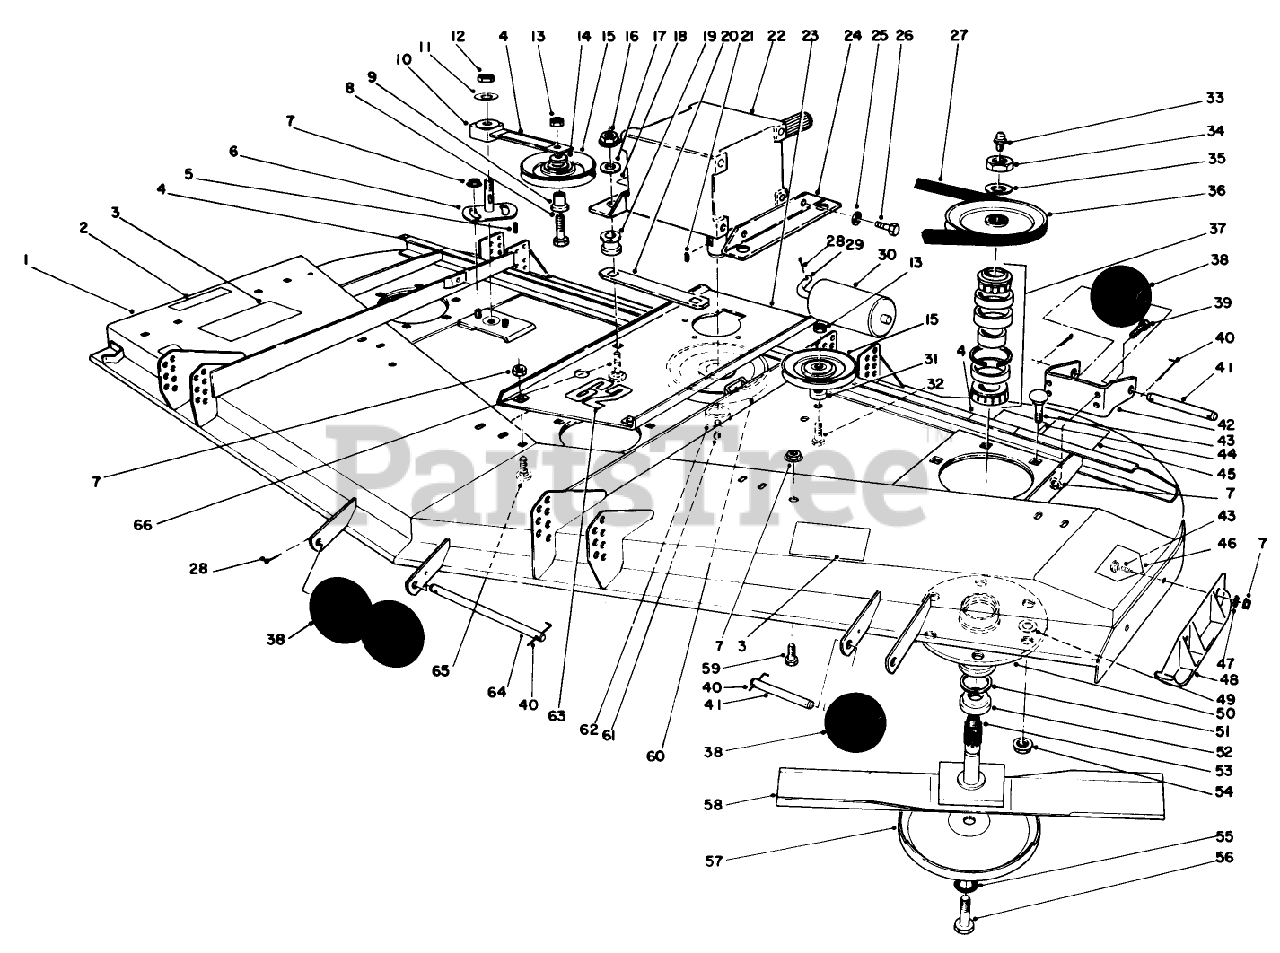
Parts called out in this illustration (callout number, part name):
1	Cutting Deck
2	DECAL-DANGER
3	DECAL-DANGER, THROWN OBJECT
4	DECAL-DANGER
5	KEY-SQUARE
6	PLATE-IDLER
7	NUT-HHF, WHIZ
8	SCREW-HH
9	BUSHING-PULLEY
10	IDLER ARM ASM
11	WASHER-FLAT
12	NUT-LOCK, NI
13	NUT-HEX
14	WASHER-FLAT
15	PULLEY-IDLER
16	NUT-LOCK, SIDE
17	WASHER
18	DECAL-OIL
19	MOUNT
20	Cover-Gear Box
21	KEY-WOODRUFF
22	Gearbox
23	Base-Gearbox
24	Bracket-Gearbox
25	WASHER-LOCK
26	SCREW-HH
27	V-BELT
28	PIN-COTTER
29	SHAFT-ROLLER, REAR
30	ROLLER-DECK
31	SPACER
32	SCREW-HH
33	FITTING-GREASE
34	NUT-HEX
35	WASHER
36	PULLEY AND HUB ASM
37	BEARING ASM
38	ROLLER
39	SCREW-HH
40	PIN-SPECIAL
41	SHAFT-ROLLER
42	Bracket-Roller
43	SCREW-CARR
44	DECAL-TORQUE
45	DECAL-WARNING
46	DECAL-DANGER
47	LOCKWASHER-PYRAMID
48	Skid
49	WASHER-FLAT
50	HOUSING-SPINDLE
51	SEAL-OIL
52	SPACER
53	SHAFT
54	NUT-HF
55	WASHER
56	SCREW-BLADE
57	CUP-SCALP, ANTI
58	Blade
59	SCREW-HH
60	PULLEY
61	SCREW-SET, HSH
62	Bushing-Taper Lock (Incl. Ref. #61)
63	DECAL
64	SHAFT-ROLLER
65	SCREW-CARR
66	SCREW-CARR
